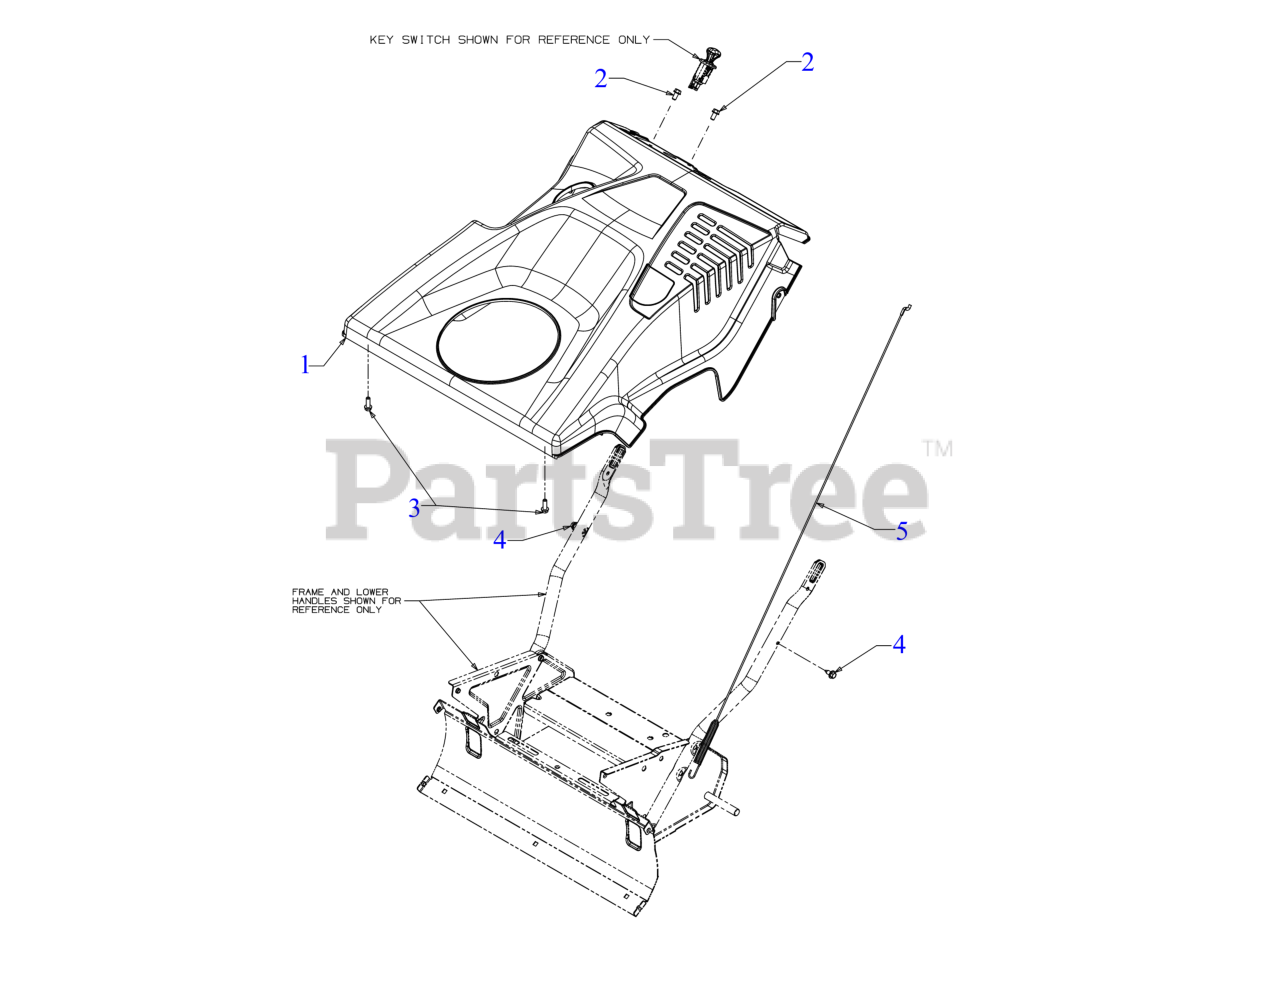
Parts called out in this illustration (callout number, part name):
1	COVER ASSEMBLY E-STYLE (BLACK)
2	HEX SCREW 1/4-15 x .50
3	SCREW 1/4-15 x .750
4	SCREW 1/4-20X.625
5	CLUTCH CABLE 35.03"
